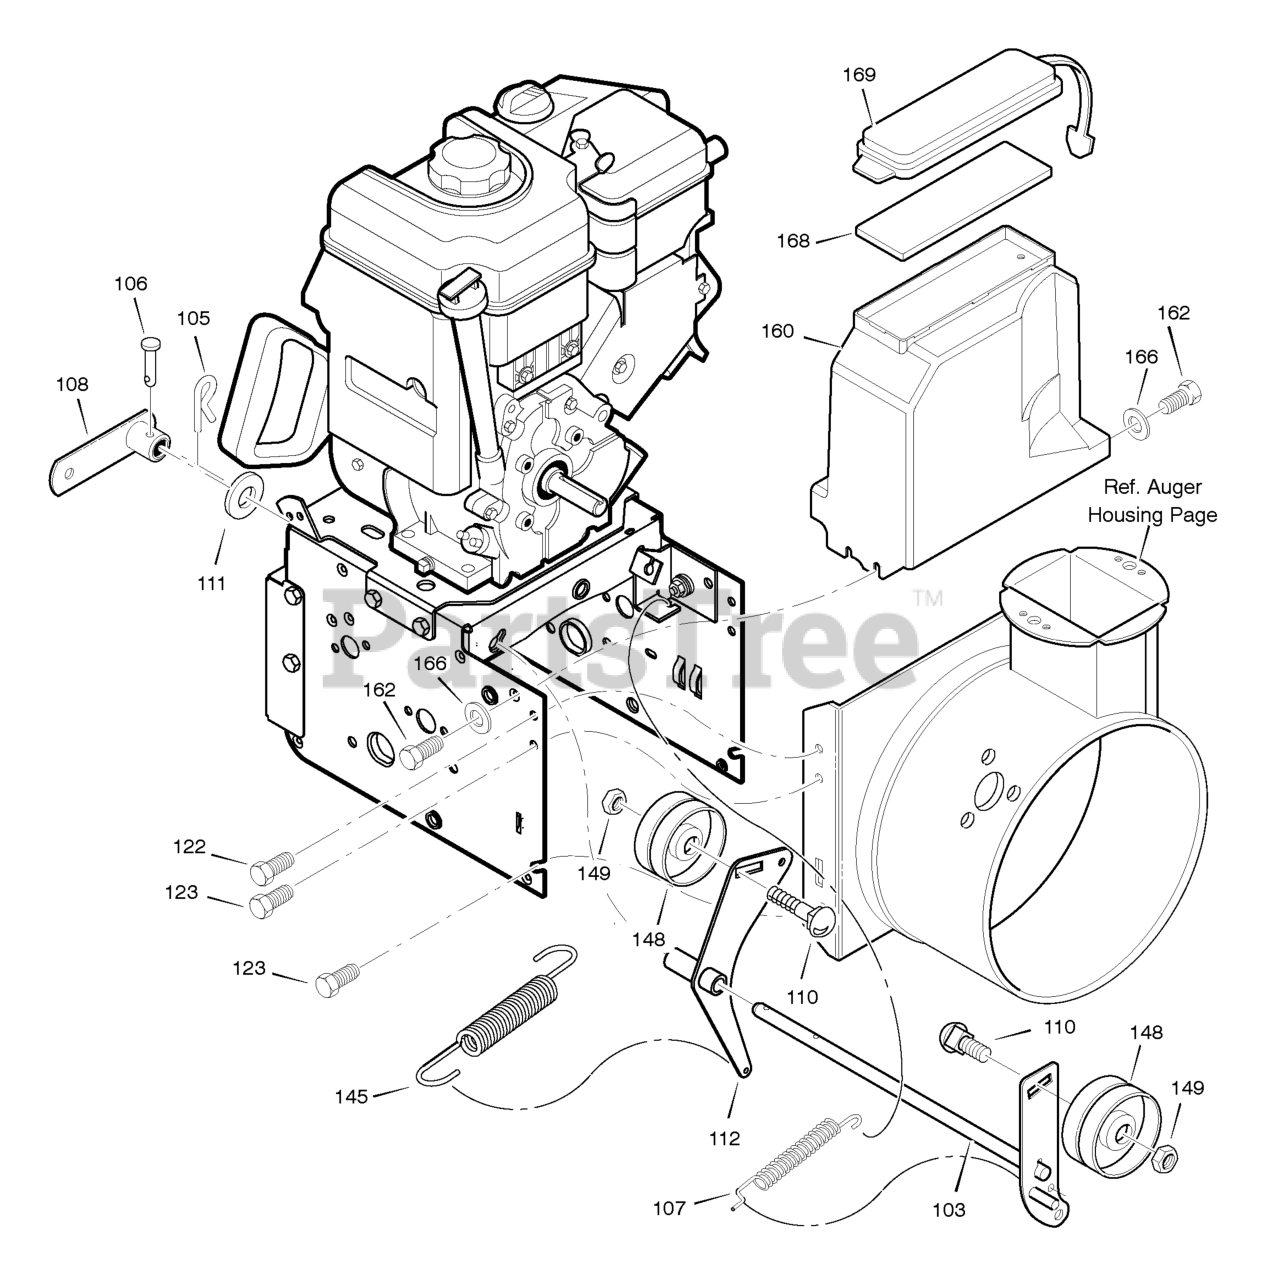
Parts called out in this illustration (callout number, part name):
103	IDLER ASSEMBLY, AUGER
105	PIN, HAIR .38DIAX1.64LG
106	PIN, CLEVIS 3/16" DIA
107	SPRING, TENSION
108	ASSY., SPRING ATTACH
110	BOLT, 3/8-16X1.25 CARR.
111	WASHER, FLAT
112	BRACKET, IDLER
122	SCREW, TAP 5/16-18 X 0.50
123	SCREW, TAP 5/16-18 X 0.75
145	SPRING, CLUTCH
148	PULLEY, IDLER
149	NUT, JAM 3/8-16
160	COVER, BELT
162	SCREW, TAP
167	WASHER, FLAT
168	PAD, FOAM
169	LID, TOOL BOX
